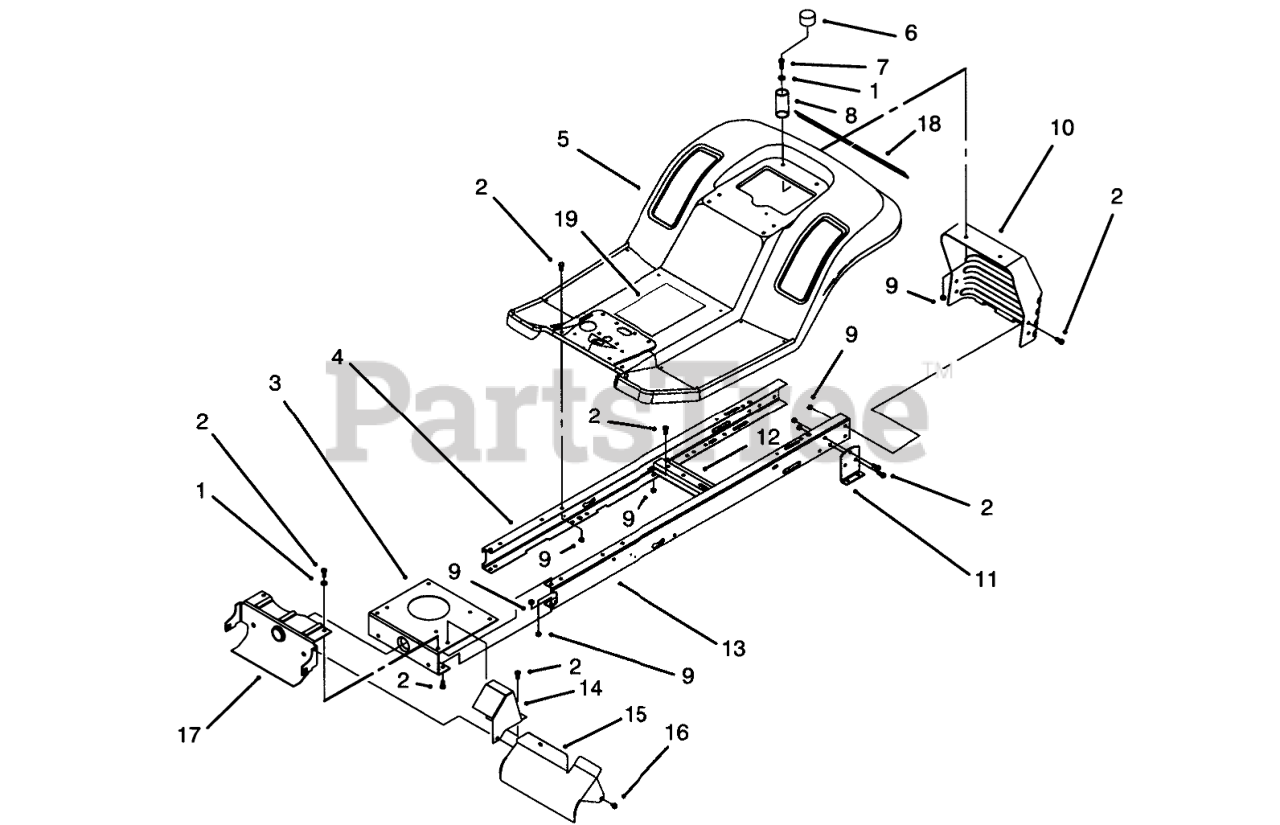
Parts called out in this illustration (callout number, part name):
1	WASHER-PLAIN
2	SCREW-HH
3	Plate-Engine Mount
4	Frame-Rail R.H.
5	BODY-REAR
6	CAP-PROTECTOR
7	SCREW-HH
8	SPRING-COMPRESSION
9	NUT-LOCK, NI
10	Panel-Rear Hitch
11	Bracket-Transaxle
12	Bracket-Idle Pivot
13	Frame-Rail L.H.
14	Shield-Exhaust Pipe
15	Shield-Muffler
16	SCREW-HWHTF
17	Support-FrontAxle
18	DECAL - REAR BODY
19	DECAL-GEAR
